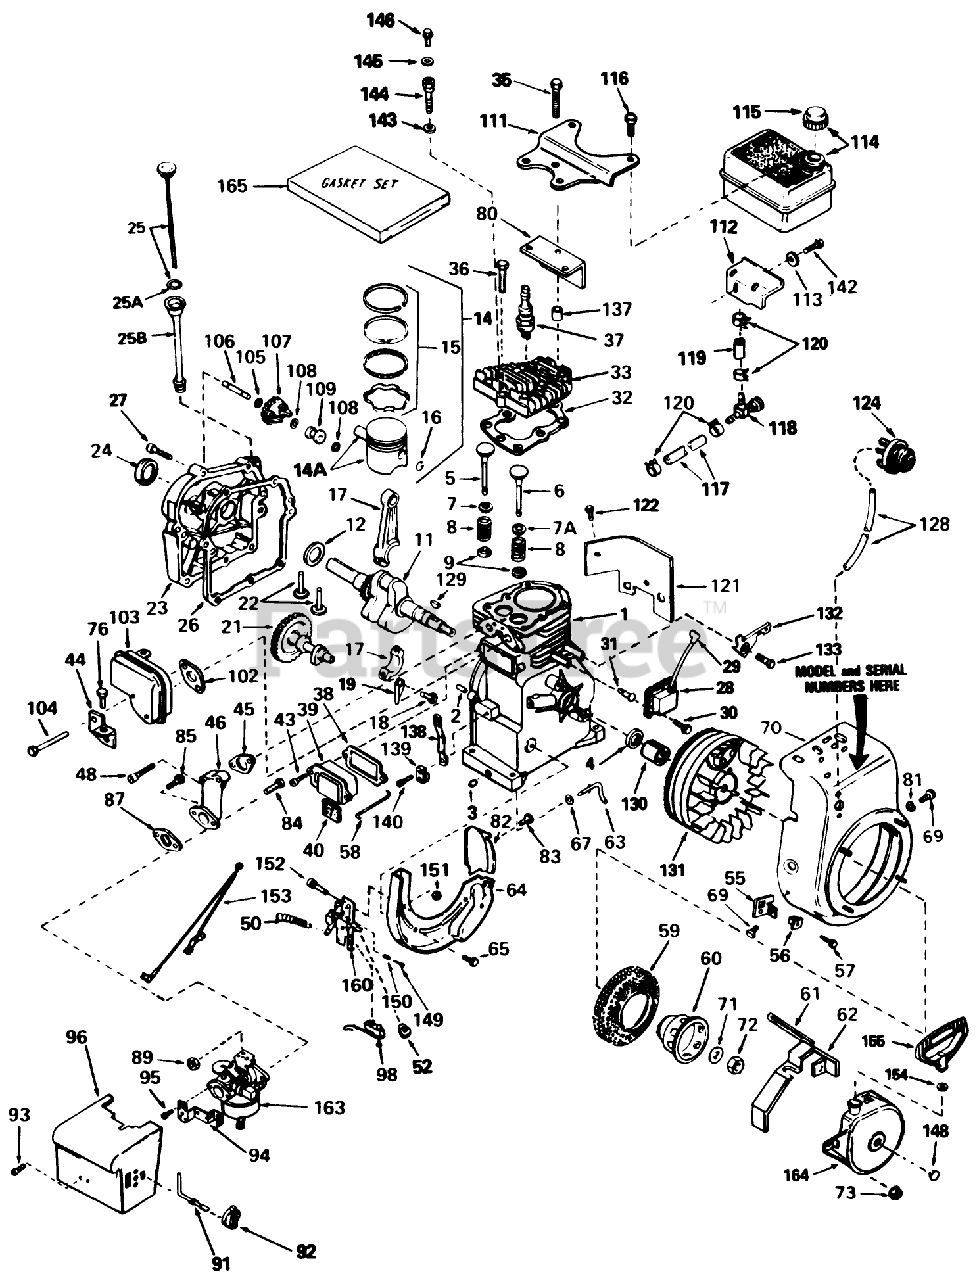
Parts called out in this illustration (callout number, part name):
1	Cylinder Assembly (Incl. Ref. #2, 3 4)
2	Pin-Dowel
3	Plug-Drain, Oil (SQH 1/4-18)
4	Seal-Oil
5	Valve-Intake Standard (Incl. Ref. #151)
5	Valve-Intake 1/32" oversize (Incl. Ref. #151)
6	Valve, Exhaust (Std.)(Incl. No. 40)
6	Valve, Intake (1/32" oversize)(Incl. No. 40)
7	Cap-Upper Valve Spring
7A	Cap, Upper Valve Spg (Exhaust)
8	Spring-Valve
9	Cap-Valve, Spring
11	Crankshaft ASM
12	Washer-Thrust
14	Piston, Pin Ring Assy., (Incl. Ref. #15 16) (Std.)
14	Piston, Pin Ring Assy., (Incl. Ref. #15 16) (.010 Oversize)
14	Piston, Pin Ring Assy., (Incl. Ref. #15 16) (.020 Oversize)
14A	Piston Pin Assy. (Incl. Ref. #16) (Std.)
14A	Piston Pin Assy., (Incl. Ref. #16) (.010 Oversize)
14A	Piston Pin Assy. (Incl. Ref. #16) (.020 Oversize)
15	Ring Set-Piston Std.
15	Ring Set-Piston .010 oversize
15	Ring Set-Piston .020 oversize
16	Ring-Retaining, Piston Pin
17	Rod Assembly, Connecting (Incl. Nos. 17 18)
18	Bolt-Rod, Connecting
19	Dipper-Oil
21	Camshaft
22	Lifter-Valve
23	Cover-Cylinder (Incl. Ref. #59 72)
24	Seal-Oil
25	Dipstick
25A	O-Ring
25B	Tube Fill
26	Gasket-Cylinder Cover
27	Screw (1/4-20 x 1-1/4)
28	Solid State
29	Cover-Spark Plug
30	Screw
32	Oil Fill Tube
33	Head Cylinder
35	Screw (5/16-18 X 2)
36	Screw (5/16-18x1-1/2)
37	Plug, Spark (J17LM or equiv.)
37	Plug, Spark (Champion RCJ-8)
38	Gasket Breather
39	Breather Assembly (Incl. Nos. 52 84)
40	Element-Breather
43	Screw
44	Bracket-Cover, Carburetor
45	Gasket-Intake
46	Pipe-Intake
48	Screw (1/4-20 x 1-19/32)
50	Spring-Extension
52	Knob-Control
55	Bracket
56	Grommet
57	Screw
58	Link-Governor to Throttle
59	Screen-Starter
60	Cup-Starter
61	Seal, Snowguard
62	Guard-Starter
63	Rod-Governor
64	Baffle-Blower Housing
65	Screw (1/4-20x19/32)
67	Washer-Flat
69	Screw
70	Housing-Blower
71	Washer-Belleville
72	Nut-Flywheel
73	Nut and Lock Washer (1/4-28)
76	Screw (10-24 x 3/8)
80	Baffle-Heat
81	Washer
82	Baffle-Extension
83	Screw-Hex Washer Hd.
85	Screw (1/4-28 x 1-11/16)
87	Gasket
89	Nut and Lock Washer (1/4-28)
91	Rod-Choke
92	Knob-Control
93	Screw (8-32 X 5/16)
94	Bracket-Choke
95	Screw (10-32 x 1/2)
96	Cover-Carburetor
98	Terminal
102	Gasket-Exhaust
103	Muffler
104	Screw-Fil. Hd.
105	Washer-Flat
106	Shaft-Governor
107	Governor Gear ASM
108	Ring-Retaining
109	Spool-Governor
111	Bracket, Fuel Tank-Upper
112	Bracket-Fuel Tank
113	Washer
114	481-1261 SENATOR TI
115	Cap, Fuel
116	Screw (1/4-15x7/8)
117	Line-Fuel
118	Valve-Shut Off
119	Line-Fuel (8.62)
120	Clamp-Line, Fuel
121	Extension-Blower
122	Screw
124	Primer Assy.
128	Line-Primer
129	Key-Flywheel
130	Spacer
131	CLAMP
132	Bracket-Hold Down
133	Screw (10-24 x 9/16)
137	pacer
138	Lever-Governor
139	Clamp-Lever, Governor
140	Screw
142	Screw Assembly
143	Washer-Flat
144	Screw ( 5/16-18 x 1-1/2)
145	Washer
146	Screw
148	Plug-Starter
149	Screw
150	Spring-Compression
151	Nut-Lock
152	Screw
153	Ground Wire
154	Washer
155	Handle-Starter, Mitten Grip
160	Control Assembly, Speed (Incl. Ref. #155 thru 158 160)
163	Carburetor (Incl. Ref. #87)
164	Starter-Rewind
165	Gasket Set
